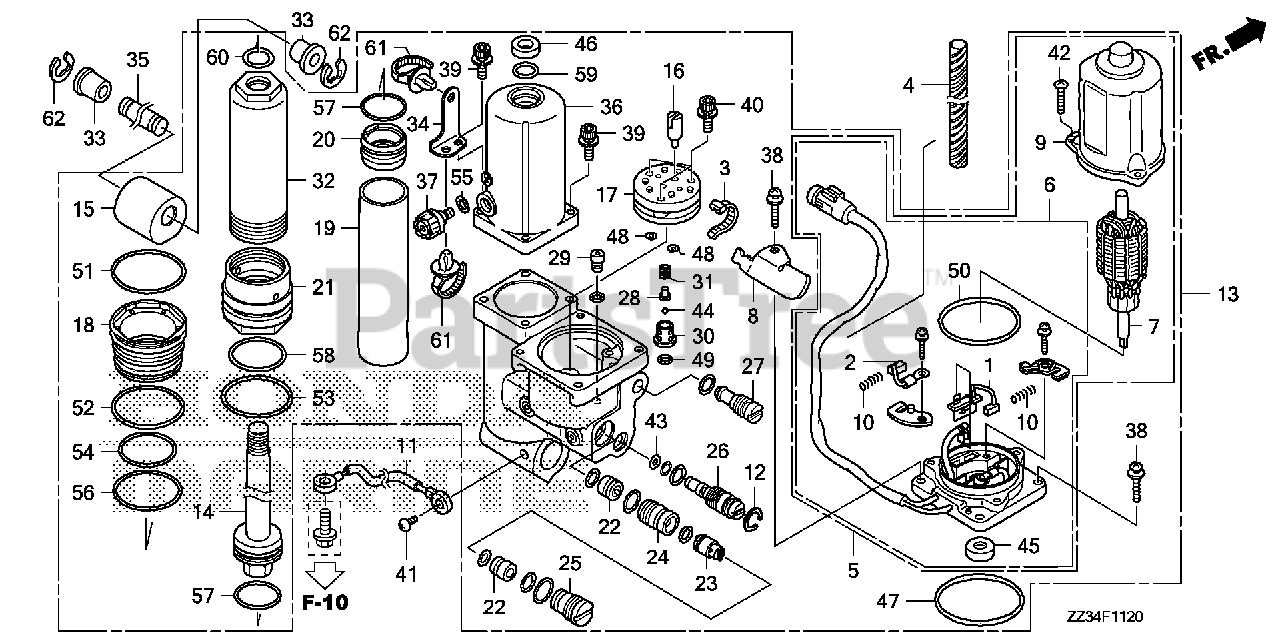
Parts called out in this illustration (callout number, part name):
1	BREAKER ASSY.
2	BRUSH ASSY.
3	BAND (BLACK 3.5X140)
4	TUBE, SPIRAL (12X14.6)
5	MOTOR ASSY., POWER TILT
6	BRACKET ASSY.
8	CLAMP, WIRE
10	SPRING, MOTOR
11	WIRE, LEAD (1.5X116MM)
12	CIRCLIP (INNER) (16)
13	TRIM-TILT ASSY., POWER
14	ROD, PISTON
15	METAL, JOINT
16	JOINT, DRIVE
18	GUIDE, TUBE (OUTER)
19	CYLINDER, TILT
20	PISTON, FREE
21	LOWER TILT CYLINDER
26	VALVE, MANUAL
28	GUIDE, SPRING
30	SEAT B, VALVE
31	SPRING, VALVE
32	TUBE (OUTER)
33	BUSH, CYLINDER (UPPER)
34	PLATE, SET
35	PIN, CYLINDER (UPPER)
37	CAP, OIL TANK
38	SCREW-WASHER
39	BOLT, SOCKET (5X0.8)
40	BOLT, SOCKET
41	SCREW, PAN (6X8)
42	SCREW, PAN (5X20)
43	WASHER, SEAL
44	BALL, STEEL
46	SEAL, WATER
47	O-RING (1.8X69.6)
48	O-RING (1.5X6.5)
49	O-RING (1.5X3.5)
50	O-RING (2.0X55.5)
51	O-RING (2.0X52.5)
52	O-RING (2.0X49.5)
53	O-RING (3.5X41.7)
54	O-RING (2.4X41.2)
55	O-RING (1.8X10.8)
56	O-RING (2.0X45.5)
57	O-RING (2.0X28.5)
58	O-RING (2.0X34.5)
59	O-RING (1.9X15.8)
60	O-RING (2.4X15.8)
61	CLIP, HARNESS BAND (145MM) (BLACK)
62	E-RING (10MM)
